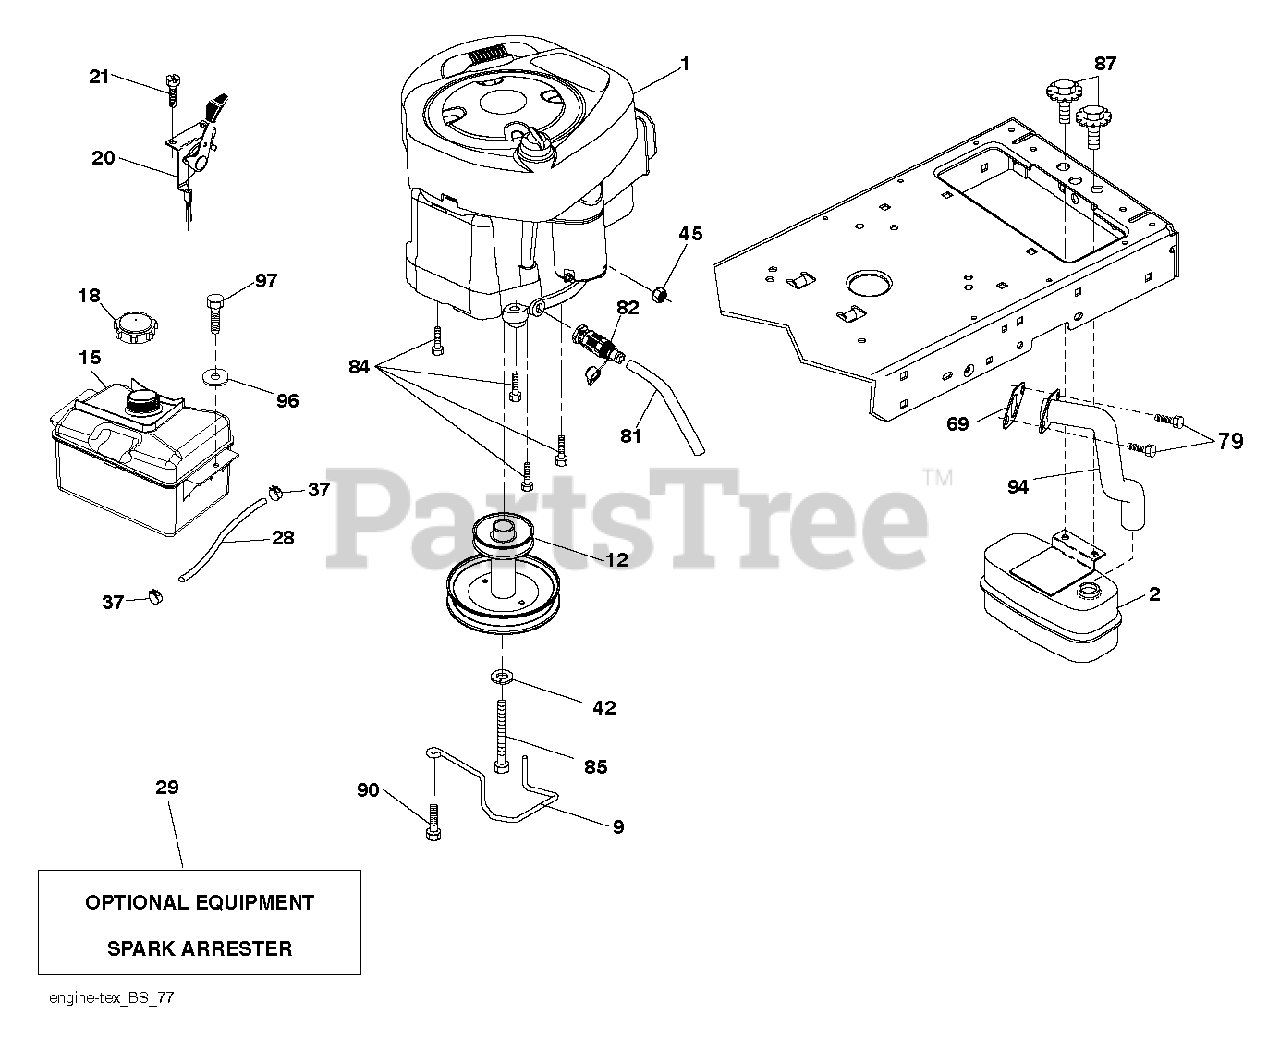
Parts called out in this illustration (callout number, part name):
2	MUFFLER.SINGLE.LRG.BRIGGS.KOHL
9	KEEPER.BELT.ENGINE.4.2
12	PULLEY ENGINE
15	FUEL.TANK.ASM.1.5.GAL.NON-EPA
18	CAP ASM.FUEL.2.25"FR.
21	SCREW.#10 X 0.750.BOS (2 2)
28	LINE.FUEL.20"FRONT.EMI
29	SPARK ARRESTOR KIT
37	HOSE CLAMP
42	LOCKWASHER
45	NUT
79	SCREW.SOCKET HD.5/16-1
81	TUBE, DRAIN OIL ASM.
82	VALUE.OIL.DRAIN
84	SCREW.3/8-16
85	BOLT HEX 7/16-20X4-1/4"
87	BOLT, 5/16-18 X 1 3/4
90	SCREW 3/8-16X1
94	RP.EXHAUST.TUBE.B&S.28/31
97	SCREW HEXWSHR 1/4-20X3/4
